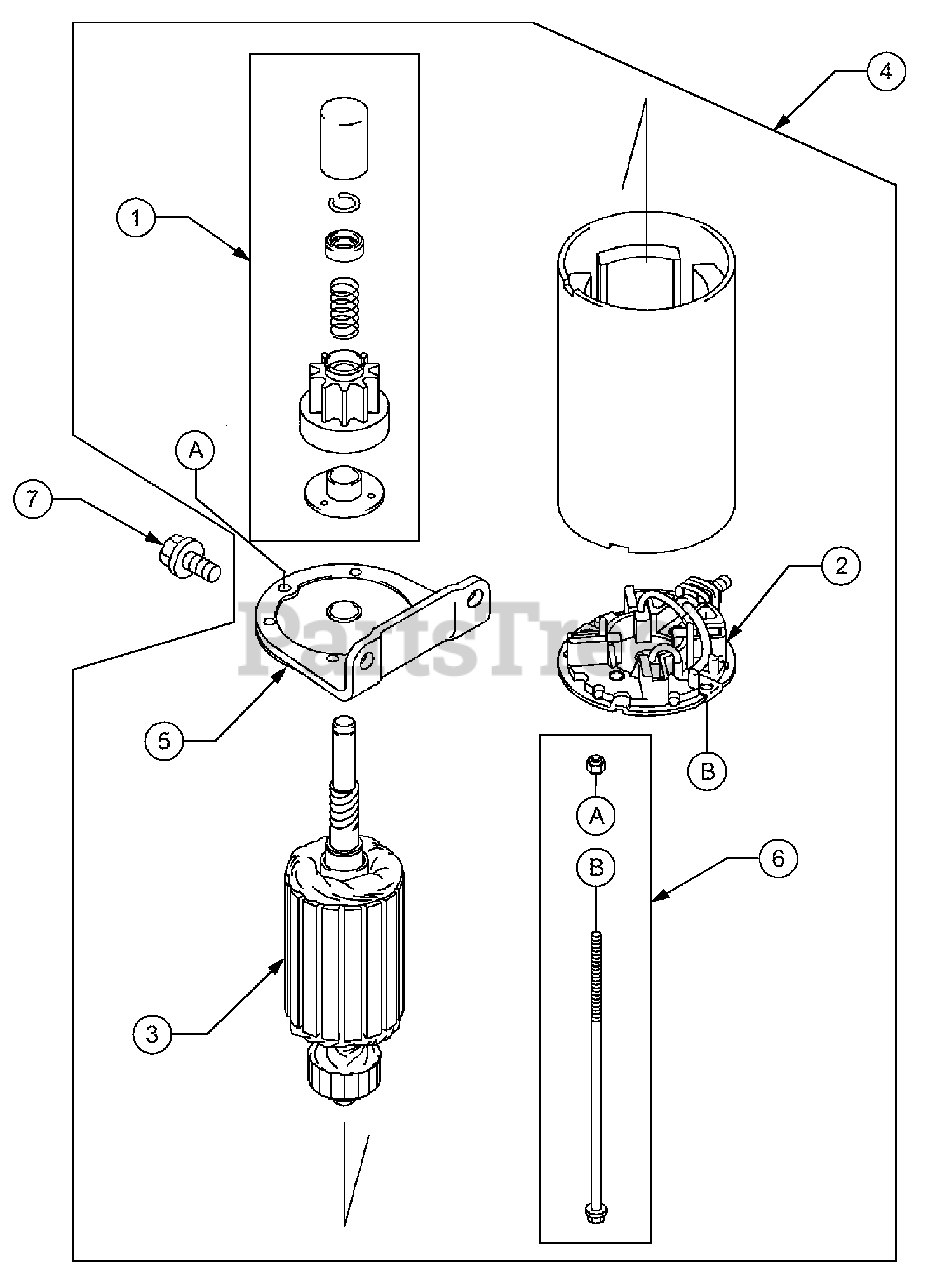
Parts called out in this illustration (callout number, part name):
1	Gear Assy
2	Brush
4	Starter, Electric
5	Bracket Ass'y.
7	Bolt, Flanged
